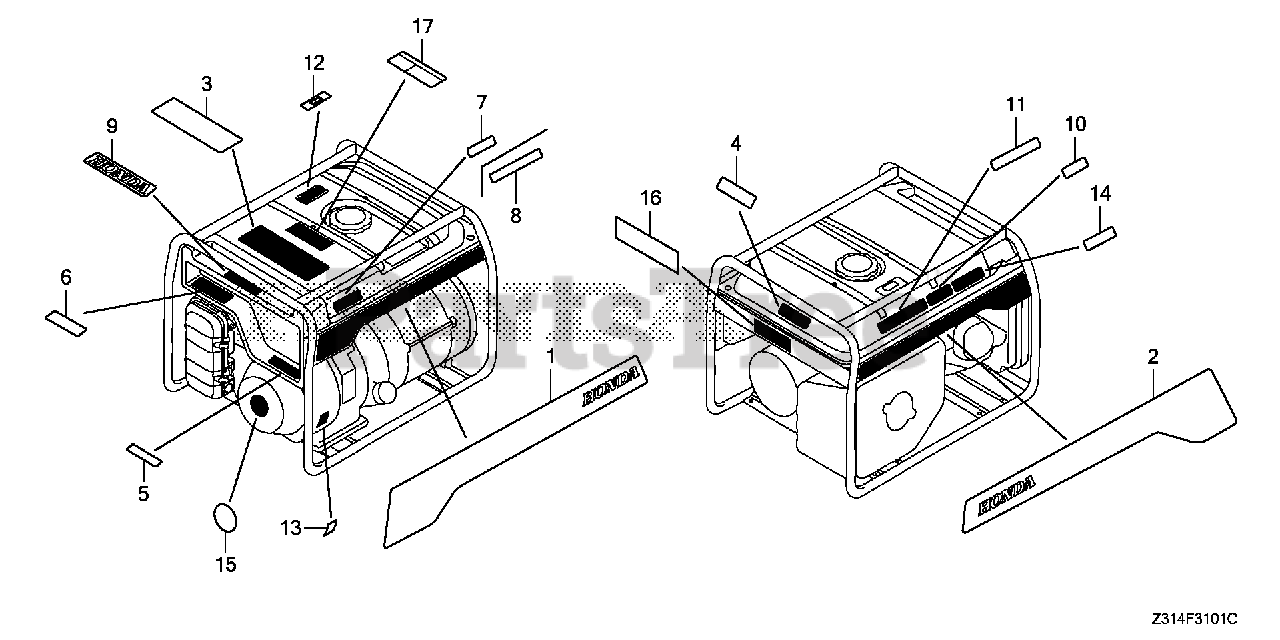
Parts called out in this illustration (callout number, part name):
1	MARK, R. EMBLEM (EG5000CL)
2	MARK, L. EMBLEM (EG5000CL)
3	LABEL, OPERATOR WARNING (E)
4	MARK, SPEC
5	MARK, FR. EMBLEM (EG5000CL)
6	MARK, OPERATION
8	LABEL, OIL ALERT
9	MARK, HONDA
11	LABEL, EX. WARNING
12	PLATE, FUEL INDICATION
13	MARK, OIL CHECK
15	MARK, HONDA
17	LABEL, FUEL WARNING (ENGLISH)
